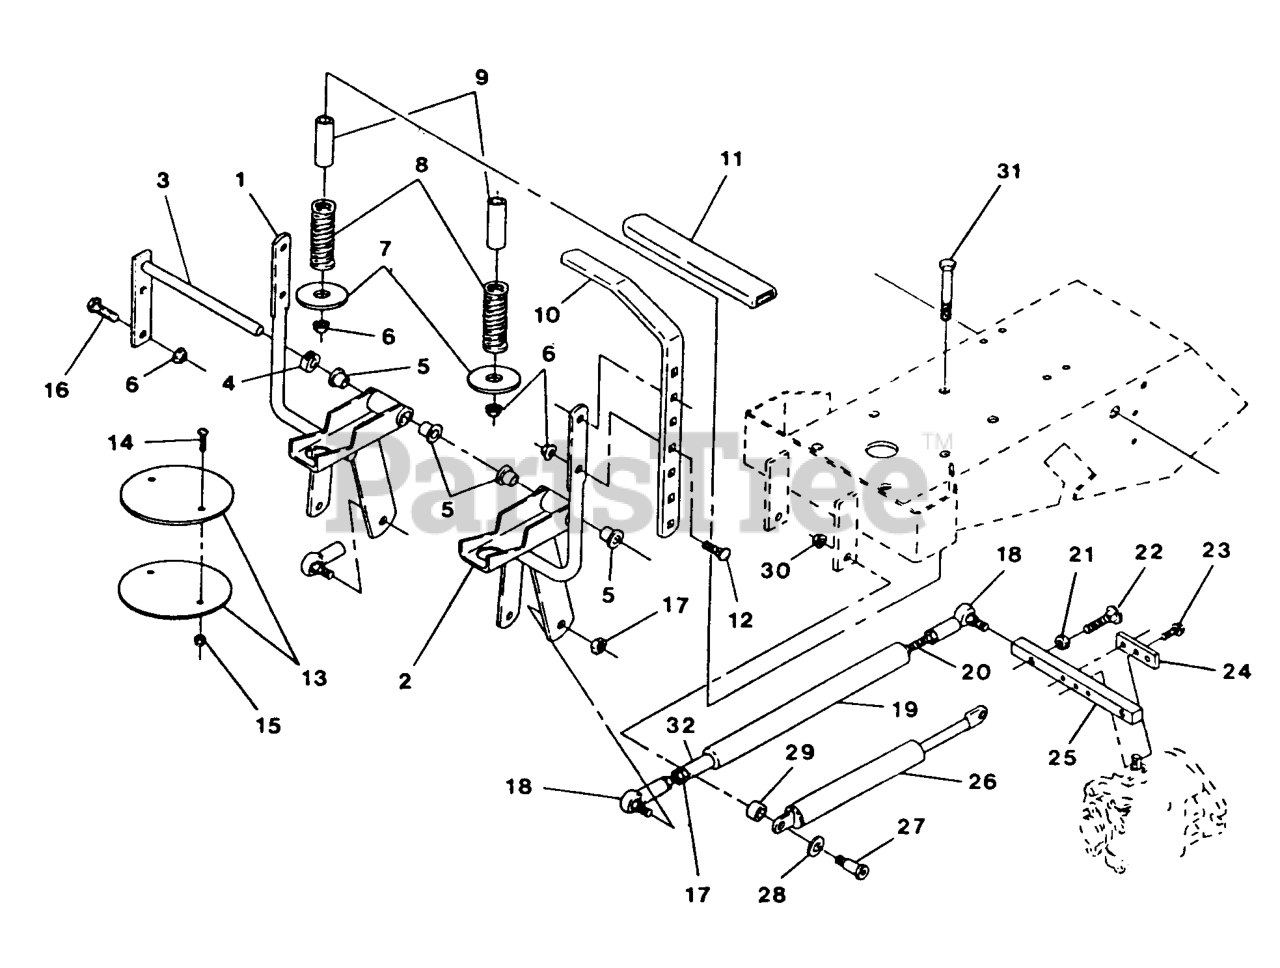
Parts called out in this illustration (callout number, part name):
5	BEARING-CONTROL
7	WSHR,REVERSE INDICATOR
8	SPRING-INDICATOR, REVERSE
9	BUSHING,SPRING GUIDE
11	GRIP,MOTION CONTRL
18	BALLJOINT
20	ROD,STEERING
24	PLATE,CLAMP
25	ARM,PUMP CONTROL
29	SPACER-PLATED
32	BUSHING,SPRING GUIDE
